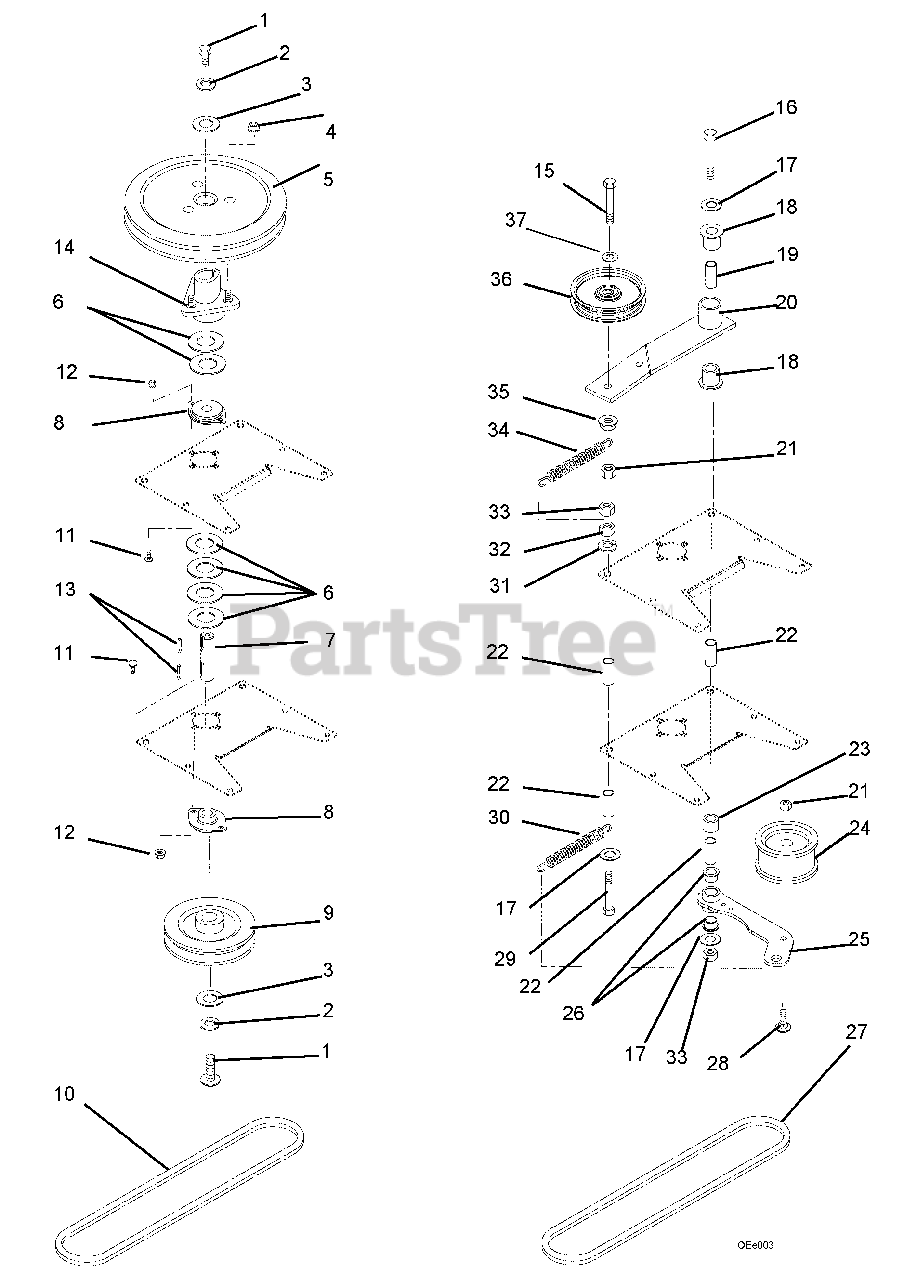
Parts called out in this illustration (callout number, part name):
1	@BLT-HEX .25-20X.75 GR5 YWZC
2	@WSHR-LK .25X.062 REG YWZC
3	WSHR-FL-STL .344X1.125X.135
4	@NUT-SPNLK-FLG .312-18 YWZC
5	PLY-V 9.0 X 1.25 3BLT
6	WSHR-FL-STL .755X1.25X.125 YZ
7	SHAFT,ZOOM SNO-THRO
8	BEARING, 2 BOLT FLANGE -.75 ID
9	SHEAVE, BLOWER - 4.25 DIA.
10	V-BELT, HA-RAW EDGE
11	@BLT-RDHDSQNK .31-18X.75 G5YZ
12	@NUT-LK-TOP-FLG .31-18 YWZC
13	KEY-SQ .187 X .50 X .187
14	24389 HUB ASSEMBLY
15	@BLT-HEX .38-16X2.25 GR5 YWZC
16	BLT-HEX .50-13X7.00 GR5 YWZC
17	@WSHR-FL-STL.531X1.06X.095YWZC
18	BSHG-FLG .762X1.0X.580X1.48 NY
19	BUSH.,S.560X.745X2.04 ST
20	WMT,IDLER
21	@NUT-LK-CTR-JAM .375-16 YWZC
22	BSHG-SLV .500X.750X1.560
23	BUSHING, .516X1.000X1.050 LG
24	IDLER FLANGED 3.50
25	WMT, IDLER ARM
26	BSHG-FLG 0.75X0.875X.625X1.125
27	V-BELT, HA-RAW EDGE
28	@BLT-RDHDSQNK .38-16X1.75 G5YZ
29	@BLT-HEX .50-13X5.00 GR5 YWZC
30	SPRING, EXTENSION
31	@WSHR-LK .50X.125 REG YWZC
32	@NUT-HEX .50-13 YWZC
33	NUT-LK-CTR-JAM .50-13 YWZC(ND)
34	SPRING, EXTENSION
35	@NUT-SPNLK-FLG .375-16 YWZC
36	IDLER, FLG .38ID X 3.50
37	@WSHR-FL-STL.406X.812X.065 YWZ
